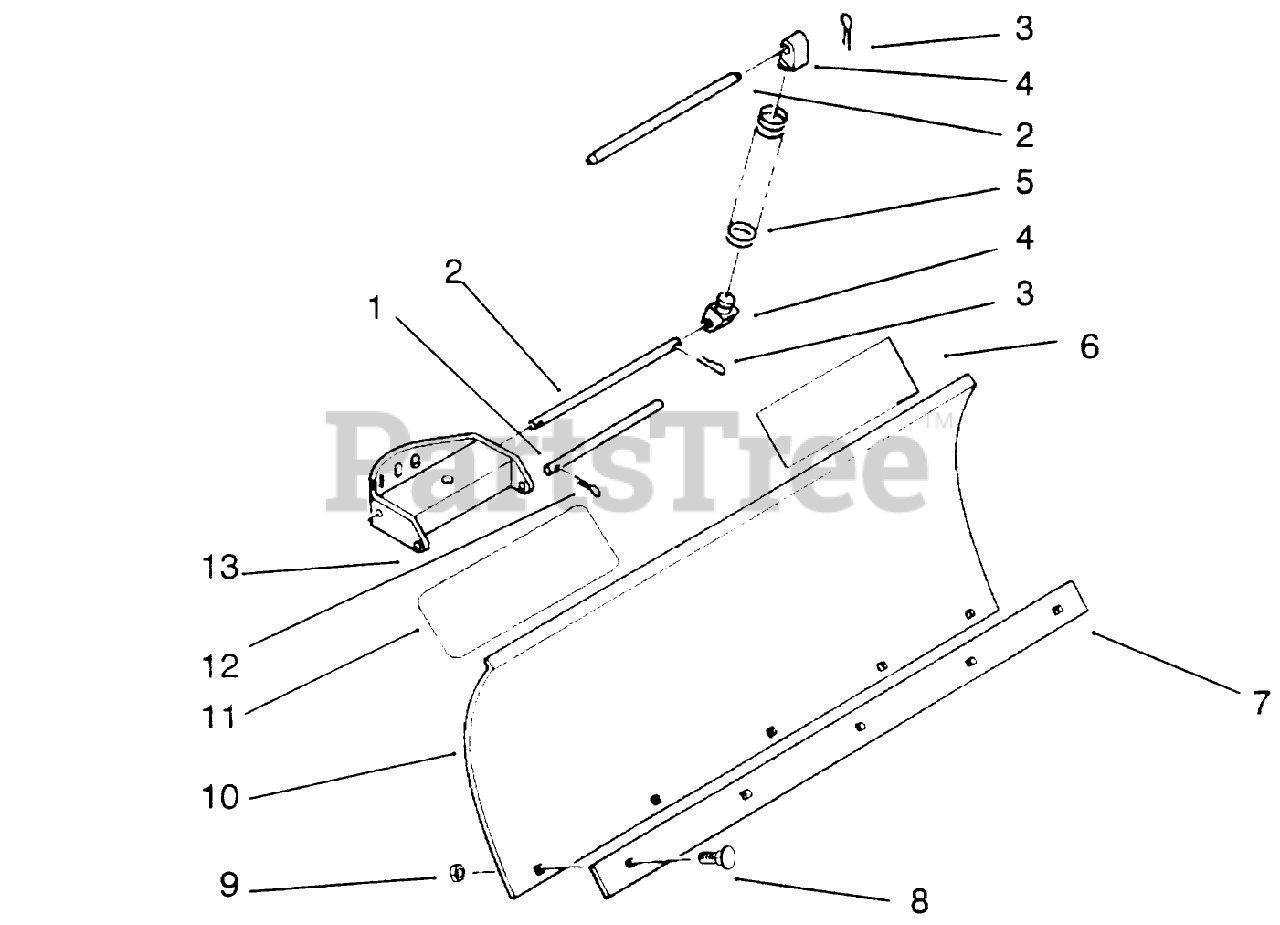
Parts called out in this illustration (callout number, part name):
1	ROD-LOWER
2	ROD-PIVOT, BLADE
3	PIN-COTTER
4	Lug
5	Spring
6	Decal
7	Blade Edge Plate
8	SCREW-CARR
9	NUT-LOCK, NI
10	Blade (Incl. Ref. #11)
11	DECAL-DANGER
12	PIN-HAIR
13	Decal
